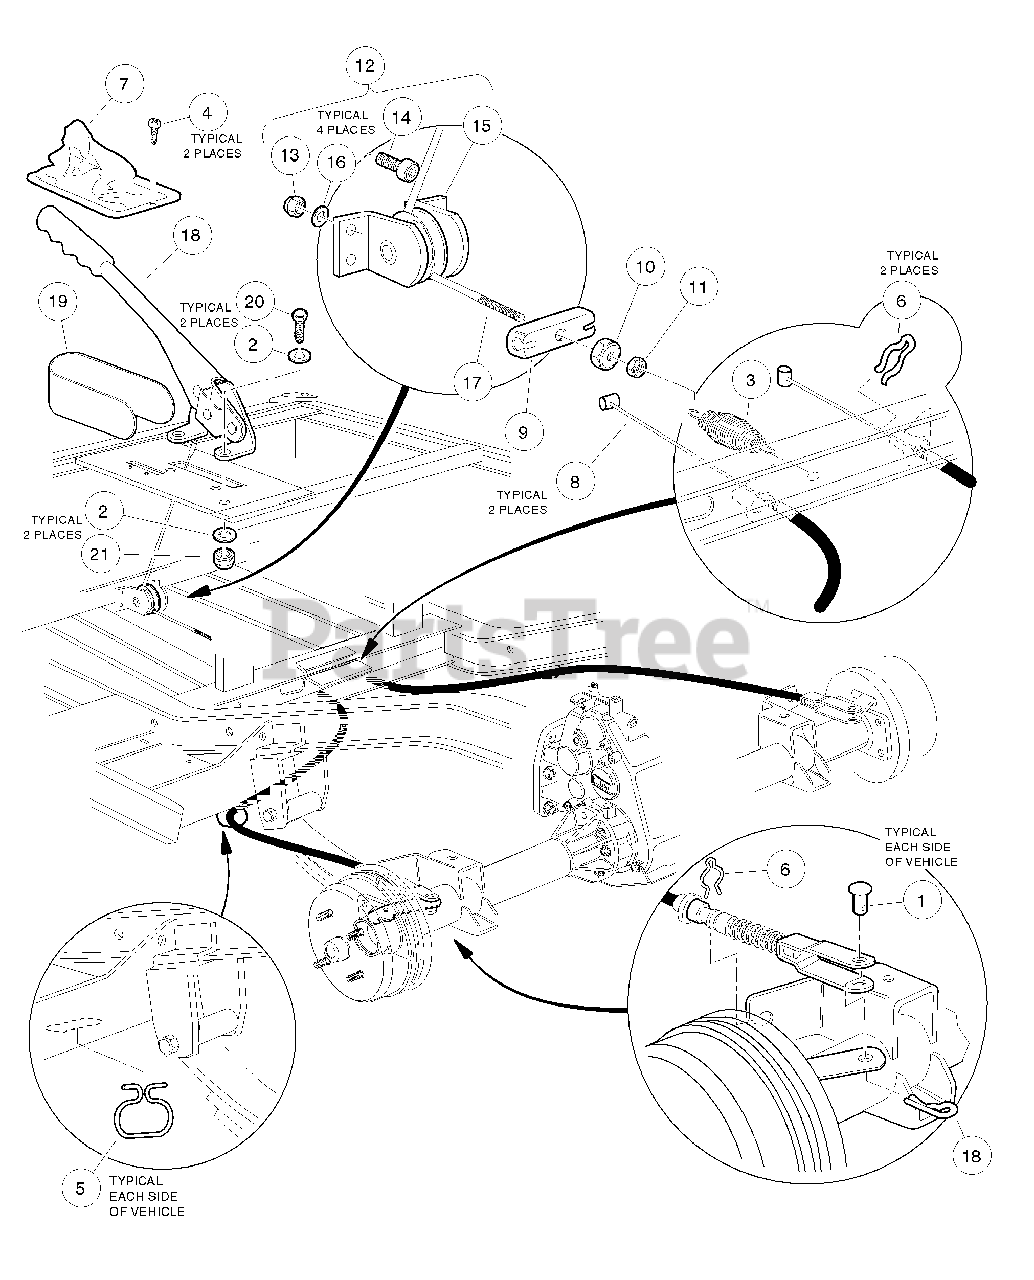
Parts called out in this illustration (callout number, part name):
1	Pin, Clevis, 5/16 X 3/4
2	Washer, 3/8 Flat
3	Spring, Brake Return
4	Screw, #7-19 X 0625 Phillips Pan-Head Tap
5	Hanger, Brake Cable
6	Park Brake Cable Clip
7	Park Brake Boot
8	Cable, Long Parking Brake
10	Nut, 5/16-24 Hex Cone
11	Nut, 5/16-24 Hex
12	Pulley Kit
13	Locknut, #10-24 Nylon Insert
14	Screw, #10-24 X 3/4 Socket-Head
15	Pulley, 2-Inch Flat Mount
16	Washer, #10 Type A Flat
17	Cable, Park Brake
18	Pin, Bow Tie Locking - 072
19	Lever, Box
20	Shield, Boot
21	Screw, Cap-hex Hd 3/8-16x125
22	Locknut, 3/8-16 Hex
